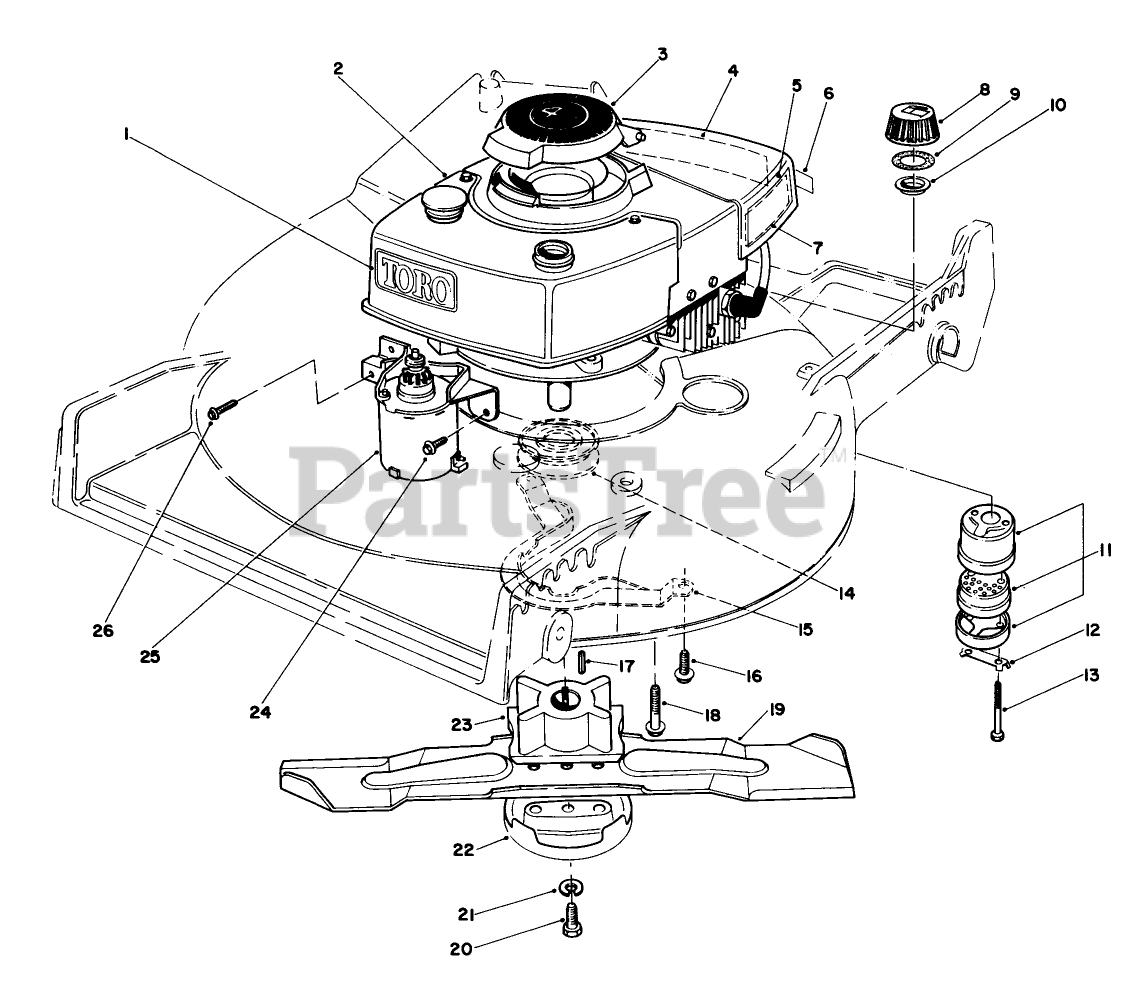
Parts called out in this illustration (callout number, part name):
2	Engine
9	GASKET
11	MUFFLER ASM
12	CLIP - LOCKING
13	SCREW-HH
17	KEY-SQUARE
18	3/8-16 X 2 CAPSCREW
20	SCREW-BLADE
21	WASHER-LOCK
23	BLADE RETAINER(DEEP)
24	SCREW
